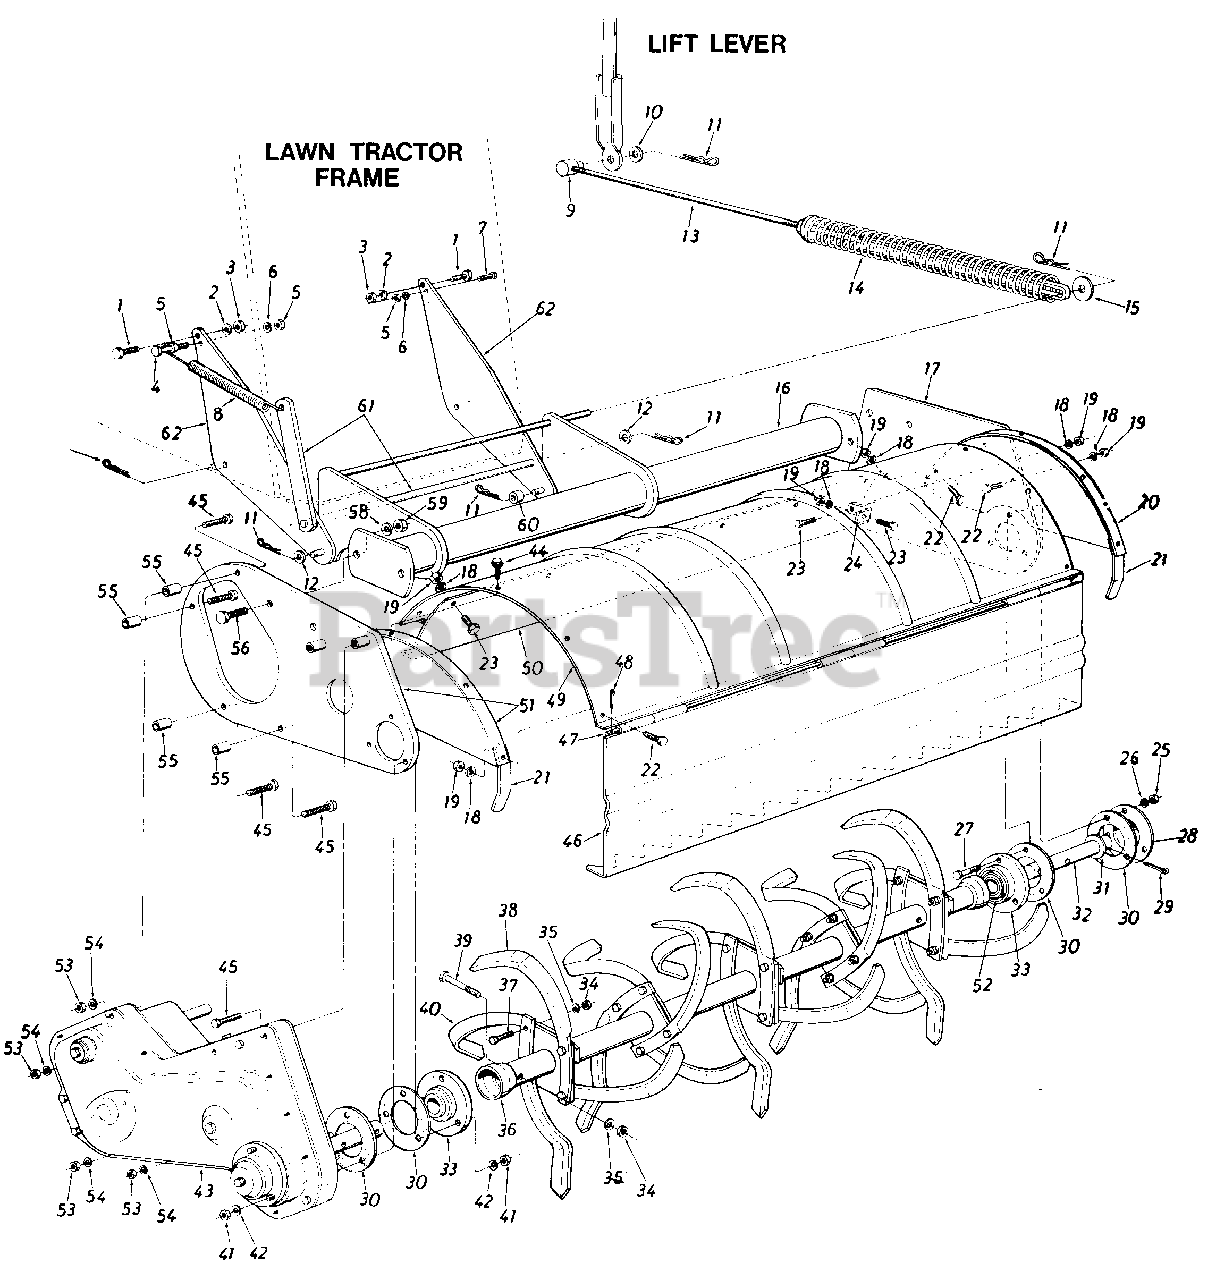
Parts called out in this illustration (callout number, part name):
1	Hex Bolt 3/8-24 x .88" Lg.*
2	L.-Wash. 3/8" I.D. Heavy Duty
3	Hex Nut 3/8-24 Thd.*
4	Hex Bolt 5/16-24 x 1.50" Lg.*
5	Hex Nut 5/16-24 Thd.*
6	L.-Wash. 5/16" I.D.*
7	Hex Bolt 5/16-24 x 1.00" Lg.*
8	Extension Spring .56" O.D. x 7.75" Lg.
9	Adjustment Ferrule 1/2-13 0 Thd.
10	Fl.-Wash. .640" I.D. x 1.24" O.D. x .060
11	Intern. Cotter Pin 1/2" Dia.
12	Fl.-Wash. .510" I.D. x 1.0" O.D. x .060
13	Lift Rod Ass'y. 39.0" Lg.
14	Compression Spring 1.50" O.D. x 15.0" Lg.
15	Fl.-Wash. .51" I.D. x 1.50" O.D. x .075
16	Pivot Bracket Assembly
19	Hex Nut 5/16-24 Thd.*
23	Hex Bolt 5/16-24 x .62" Lg.*
24	Chute Pivot Bracket
25	Hex Cent. L-Nut 5/16-18 0 Thd.
26	L.-Wash. 5/16" I.D.*
27	Hex Bolt 5/16-18 x 1.0" Lg. (Grade 5)
30	Gasket for Brg. Housin
31	Fl.-Wash. 1.25" I.D. x 2.00" O.D. x .06
32	Tine Shaft R.D. 1.25" Dia. x 6.25" Lg.
33	Bearing Housing w/Bearin
34	Hex Nut 3/8-24 Thd.*
35	L.-Wash. 3/8" I.D. Heavy Duty
38	Tine 14" x 5/16"
39	Hex Bolt 3/8-24 x 2.25" Lg.*
40	Tine 14" x 5/16"
41	Hex Cent. L.-Nut 5/16-18 0 Thd.
42	L.-Wash. 5/16" I.D.*
43	Chain Case Ass'y. Comp.
44	Hex Wash. TT Tap. Scr. 5/16-18 x .62" Lg.
45	Hex Bolt 1/4-20 x 2.75" Lg.*
48	Cotter Pin 1/8" Dia. x 1.00 Lg.
53	Hex Nut 1/4-20 Thd.*
54	L.-Wash. 1/4" I.D.*
55	Spacer .28" I.D. x .62" O.D. x .90 " Lg.
56	Hex Bolt 1/2-13 x 1.00" Lg.*
58	L.-Wash. 1/2" I.D.*
59	Hex Nut 1/2-13 Thd.*
60	Spacer.50" I.D. x 1.00" O.D. x .50" Lg.
61	Idler Bracket Support Arm Ass'y
62	Pivot Bracket Support
